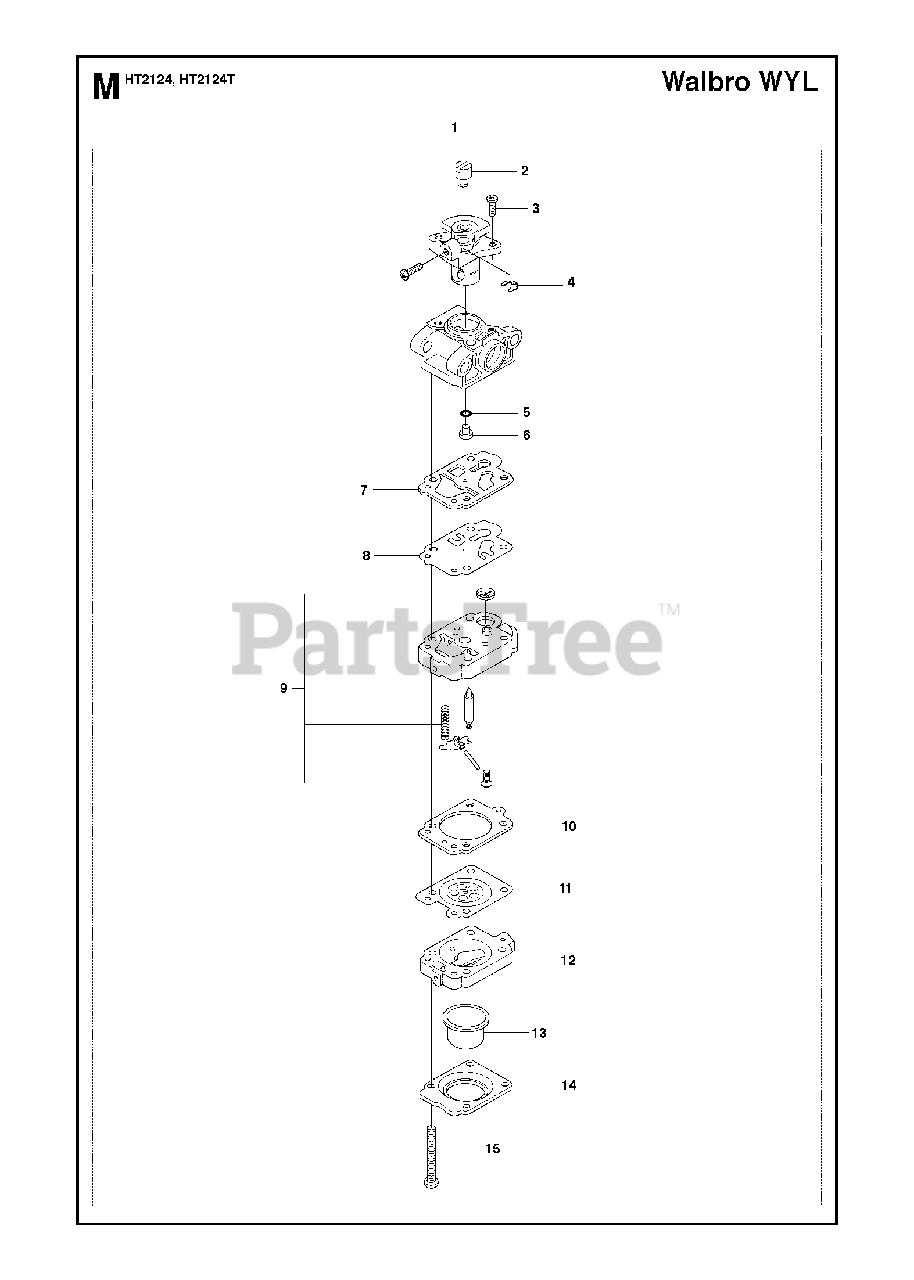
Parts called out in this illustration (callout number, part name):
1	CARBURETOR
3	SCREW
5	RING
6	JET
7	GASKET
8	%GASKET
9	HOUSING
10	GASKET
11	DIAPHRAM
12	HOUSING
13	PRIMER
14	PUMP COVER
15	SCREW
